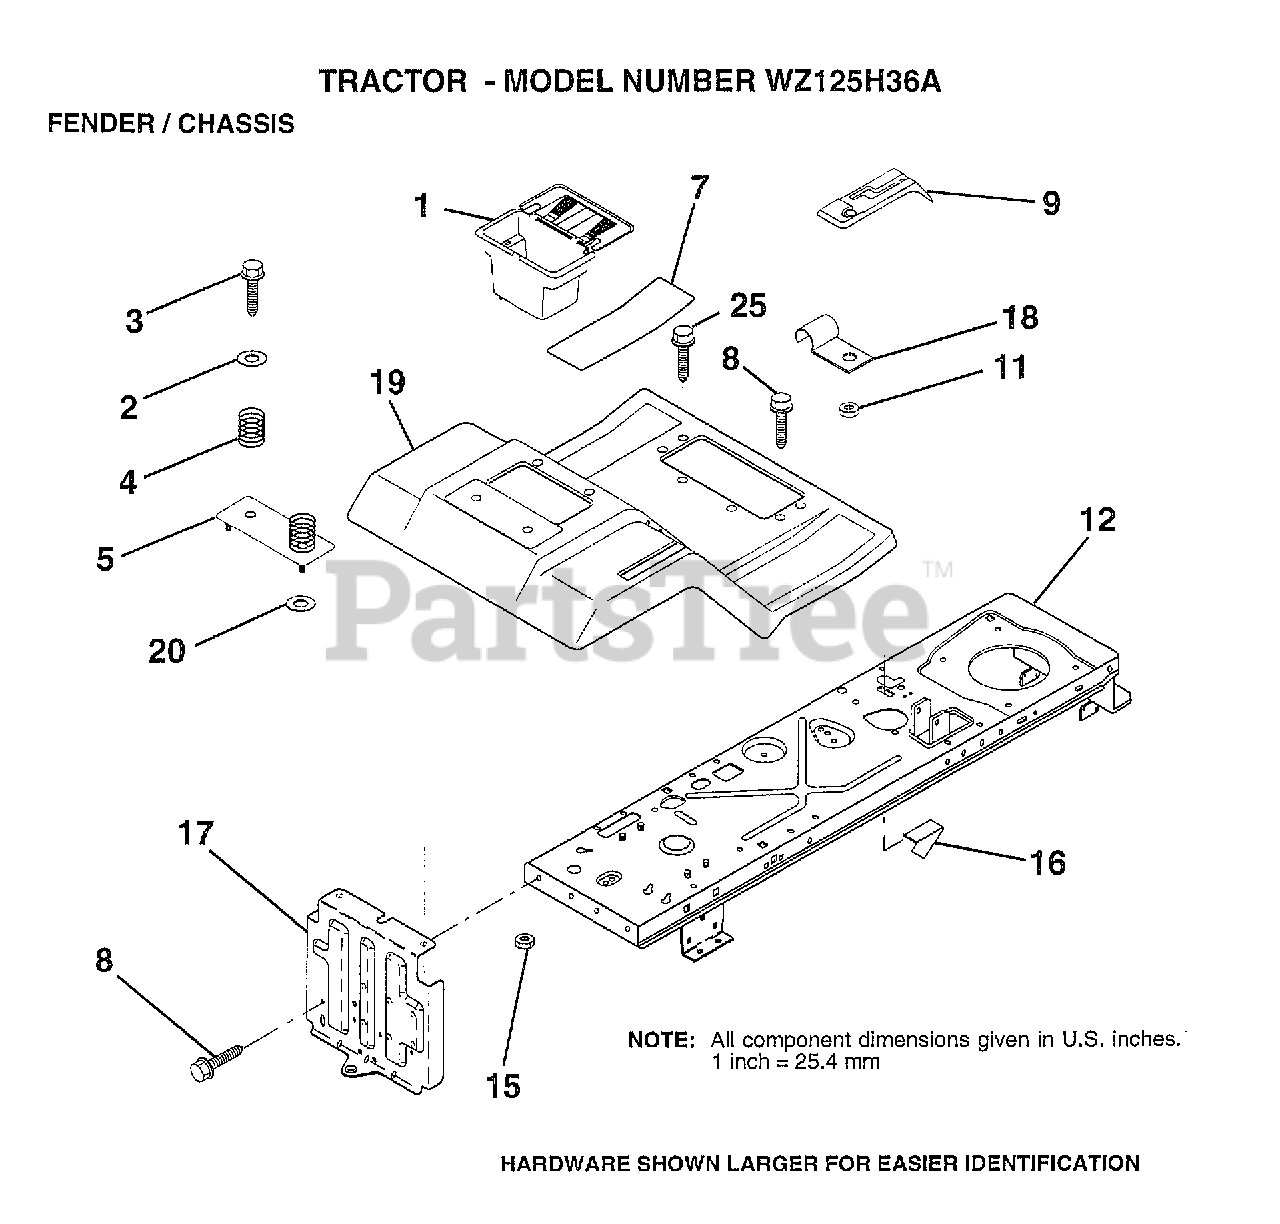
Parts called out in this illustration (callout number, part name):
1	"CASE,BATTERY.MECH"
2	WASHER
3	SCREW
4	SPRING COMPRESSIO
5	BTRY FENDER PLATE
7	PAD FOOTREST
8	SCREW
9	CONSOLE.HYD.W/IGN
10	PLATE LOCK SHIFT
11	NUT
12	CHASSIS.WELD.ASM.
15	NUT HXKEP 1/4X20
17	DRAWBAR ASM LR
18	"CLIP,INSULATOR"
19	FENDER/FOOT MS505
25	SCREW
